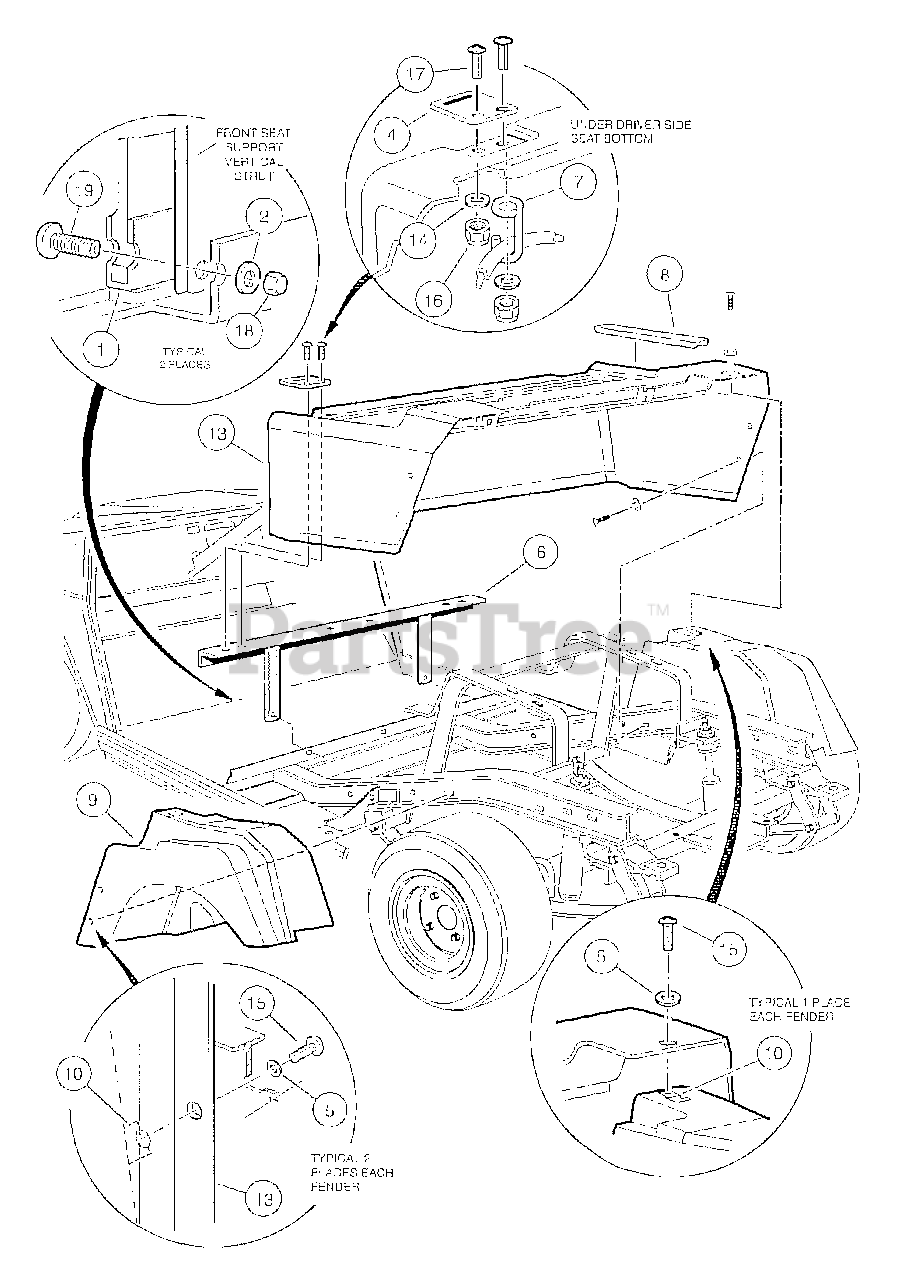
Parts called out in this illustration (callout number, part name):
1	Body Kick Plate
2	Washer, 1/4" Type B Flat
3	Body Assembly
4	Body, Hinge Plate
5	Washer, 1/4" Type B Flat
6	Body Support Front
7	Cable Retainer
8	Wear Pad
9	Fender, Driver Side
10	U-Nut, 1/4-20
11	Fender, Passenger Side
12	U-Nut, 1/4-20
13	Body, Rear, Gas
14	Washer, 1/4 Type A Narrow Flat
15	Screw, 1/4-20 X 0.75 Hex-Head Cap
16	Locknut, 114-20 Nylon Insert
17	Screw, 1/4-20 X 1.0 Truss-Head Machine
18	Locknut, 1/4-20 Nylon Insert
19	Screw, 1/4-20 X 1.0 Truss-Head Machine
